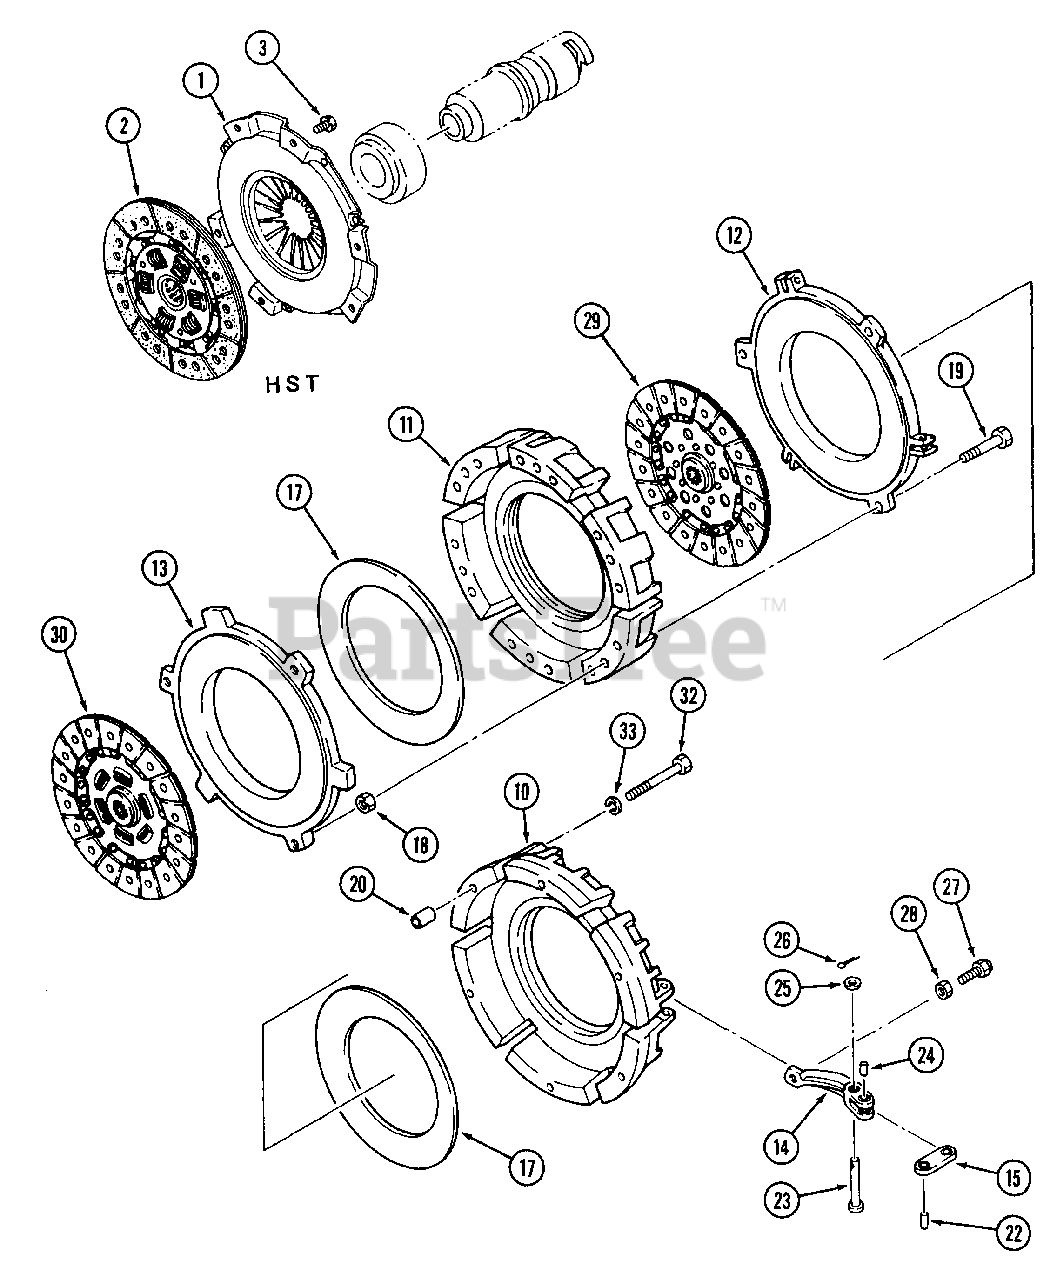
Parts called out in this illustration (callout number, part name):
1	Cover Ass'y.
2	Disc, Clutch
3	Bolt
10	Clutch, Cover
11	Clutch, Cover
12	Pressure Plate
13	Pressure Plate
14	Release Lever Sub Ass'y.
15	Release Rod Sub Ass'y.
17	Diaphragm Spring
26	Pin, Split
29	Clutch Disc Ass'y.
30	Clutch Disc Ass'y. PTO
